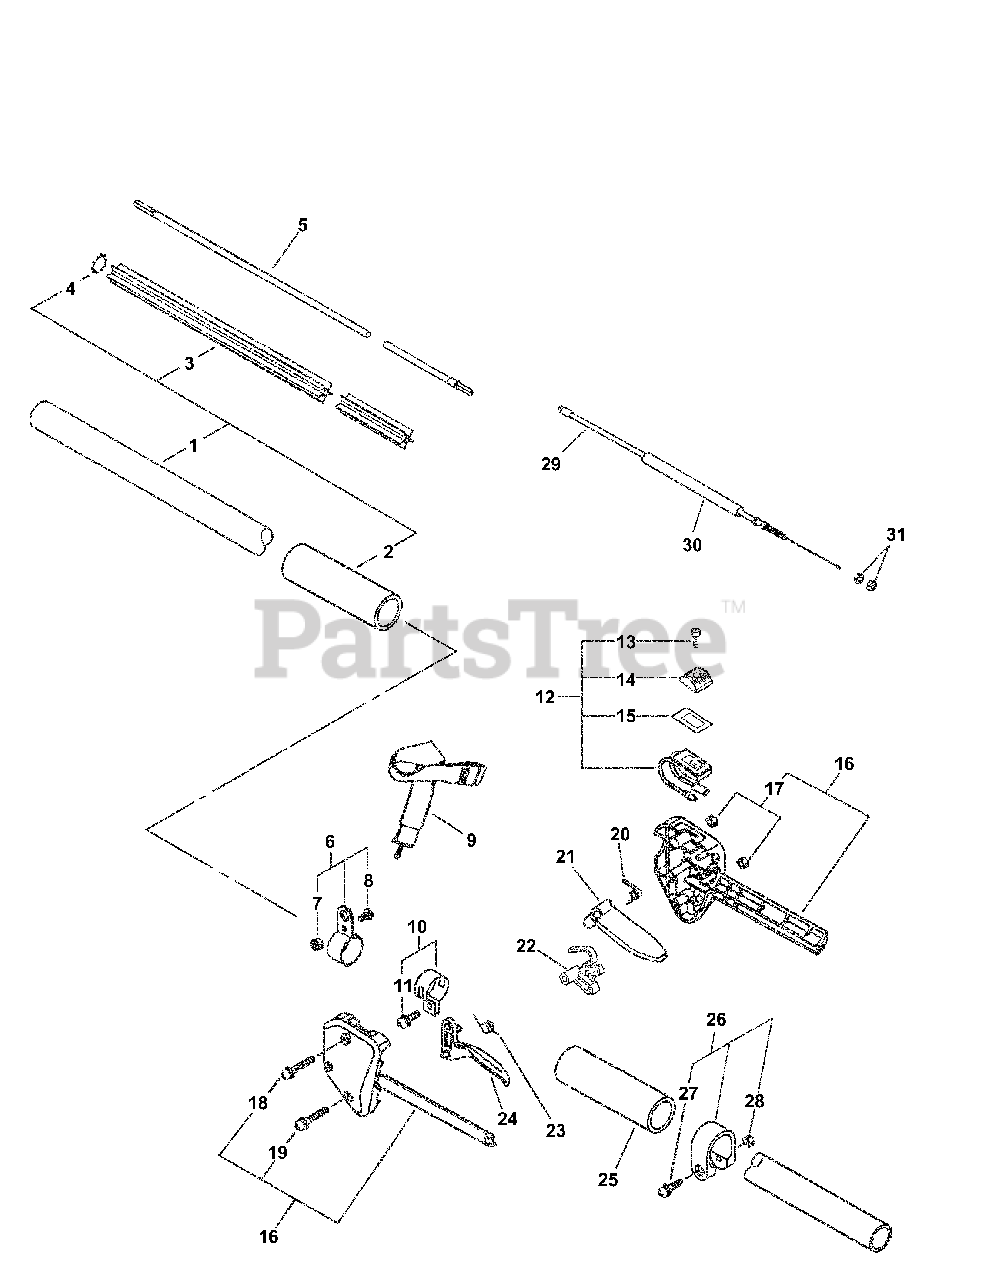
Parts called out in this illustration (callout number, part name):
1	MAIN PIPE ASSY
2	GRIP, FRONT - LEFT
3	LINER - FLEXIBLE
4	LOCKWASHER - EXTERNAL
5	DRIVESHAFT - FLEXIBLE
6	HANGER KIT
7	LOCKNUT - 10-24
8	SCREW
9	SHOULDER STRAP ASSY
10	CLAMP KIT
11	SCREW - 5X14
12	IGNITION SWITCH ASSY
13	SCREW - 3X10
14	KNOB, SWITCH - ORANGE
15	COVER, SWITCH - STOP
16	CONTROL HANDLE KIT
18	SCREW - 5X35
19	SCREW - 5X25
20	SPRING, LOCKOUT LEVER
21	LEVER, TRIGGER LOCKOUT
22	LOCKOUT, THROTTLE
23	SPRING, TRIGGER
24	TRIGGER, THROTTLE
25	GRIP, HANDLE
26	CLAMP KIT
27	SCREW - 5X28
29	CABLE, THROTTLE
